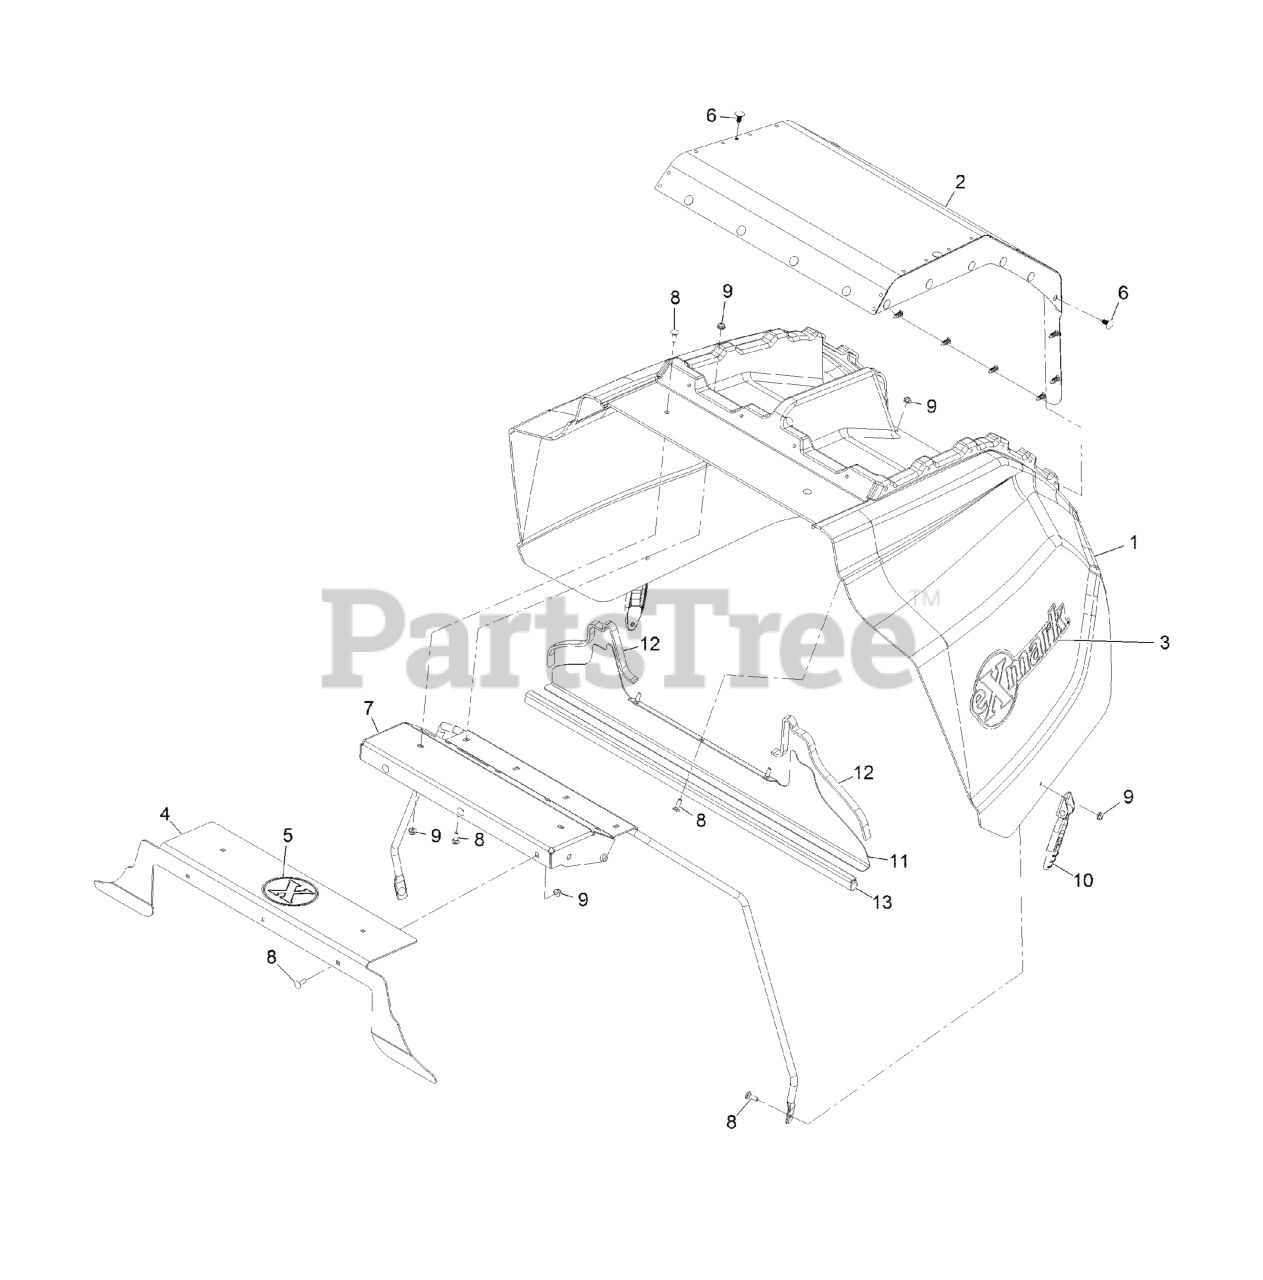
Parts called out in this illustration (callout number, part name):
1	HOOD,LZSD
2	Screen-Intake
3	DECAL-EXMARK
4	Block Off-Hood
5	DECAL-X-LOGO
6	PLUG-PLASTIC
7	SUPPORT-HOOD
8	BOLT-CARR
10	LATCH-RUBBER
11	Plate-Seal
12	SEAL-FOAM
13	Seal-Bulb
